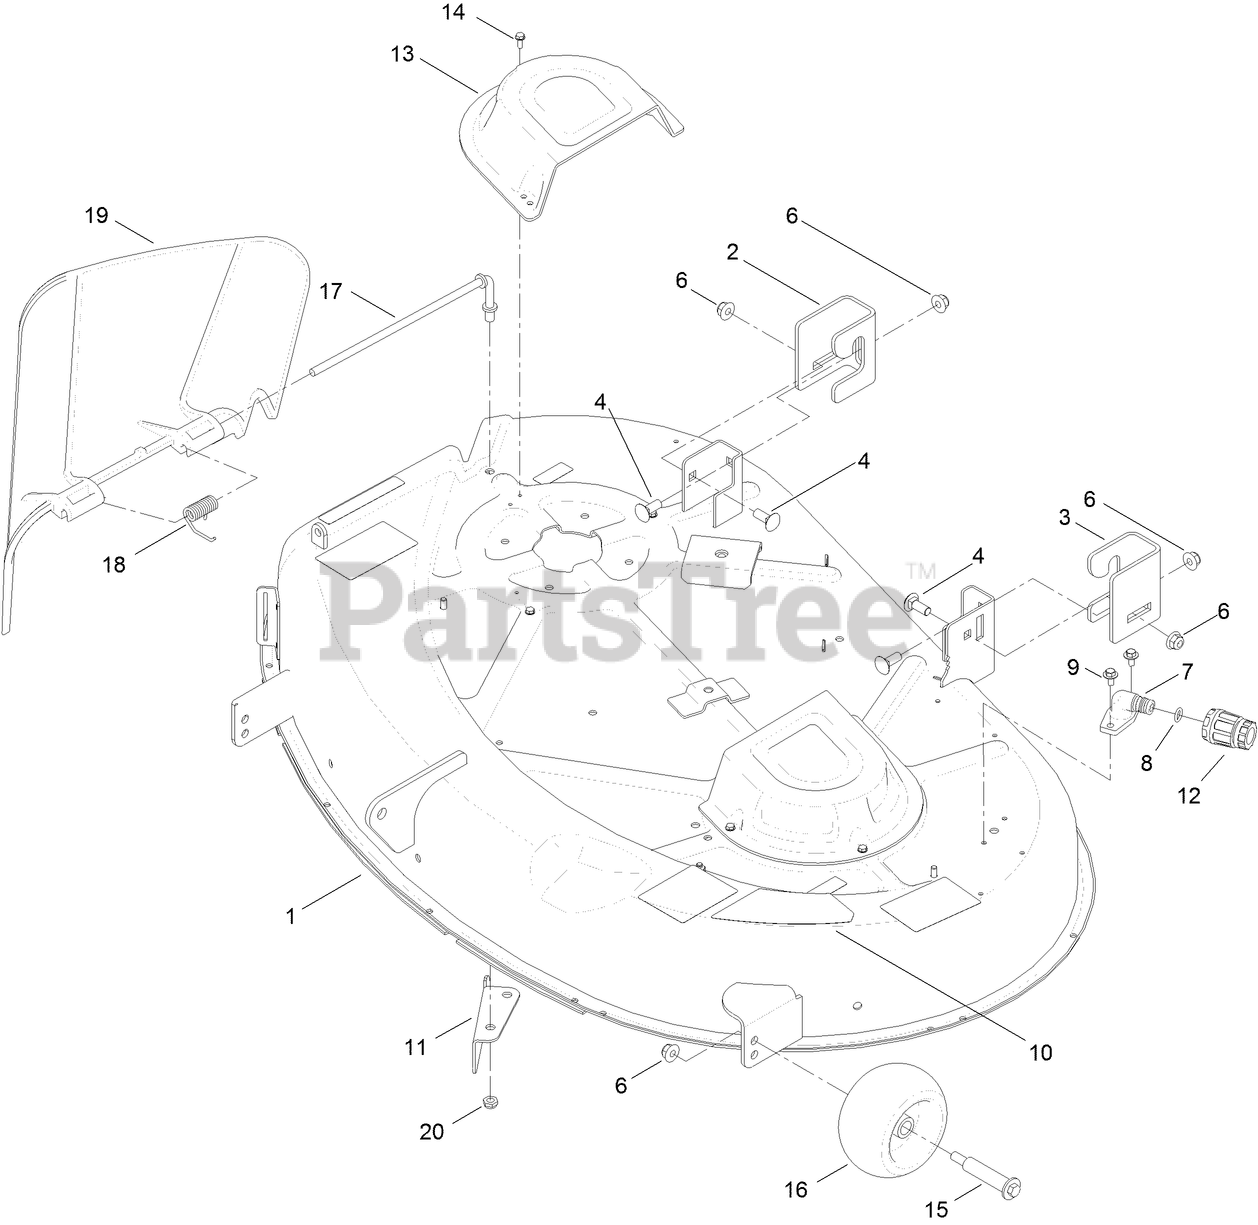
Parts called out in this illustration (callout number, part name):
1	42 INCH DECK AND DECAL ASM
3	BRACKET-HANGER, LH
4	BOLT-CARR
6	NUT-HF, NI
8	O-RING
9	SCREW-HHFTF
11	BAFFLE-CUTOFF
12	CONNECTOR-HOSE
13	COVER-BELT
14	SCREW-TAPTITE
15	BOLT-SHOULDER
16	ROLLER-SCALP, ANTI
17	ROD-PIVOT
18	SPRING-TORSION
19	DEFLECTOR
